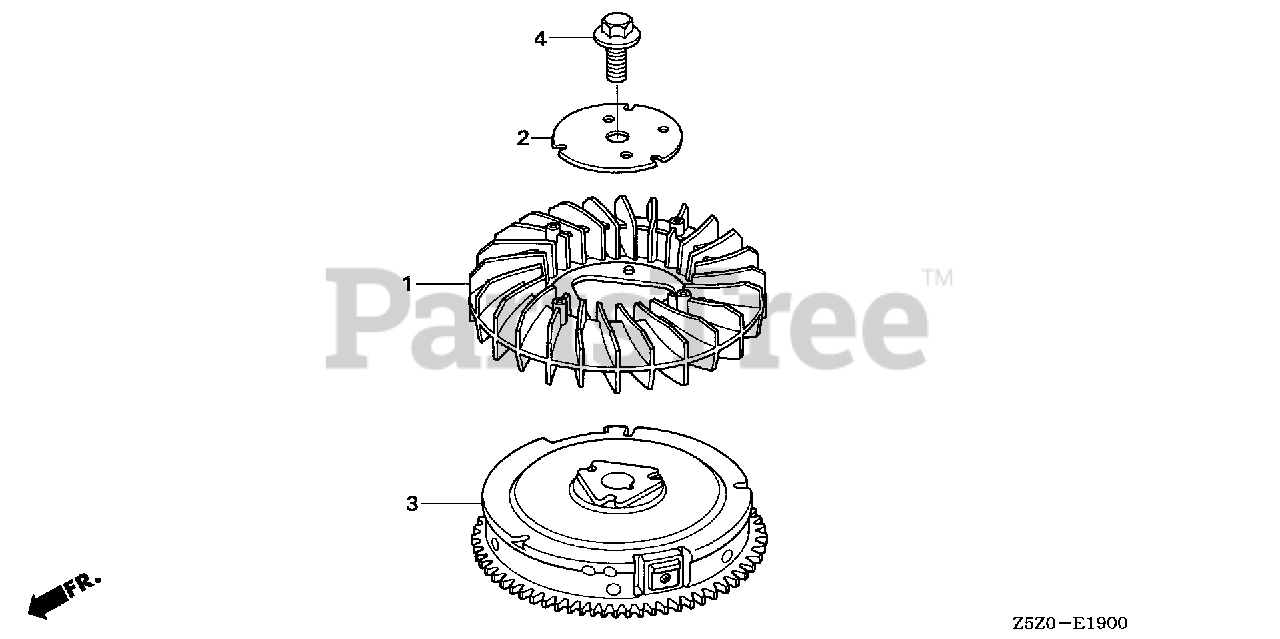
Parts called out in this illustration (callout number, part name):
1	FAN, COOLING
2	PLATE, COOLING FAN SETTING
3	FLYWHEEL (6P)
4	BOLT, FLANGE (16X35)
